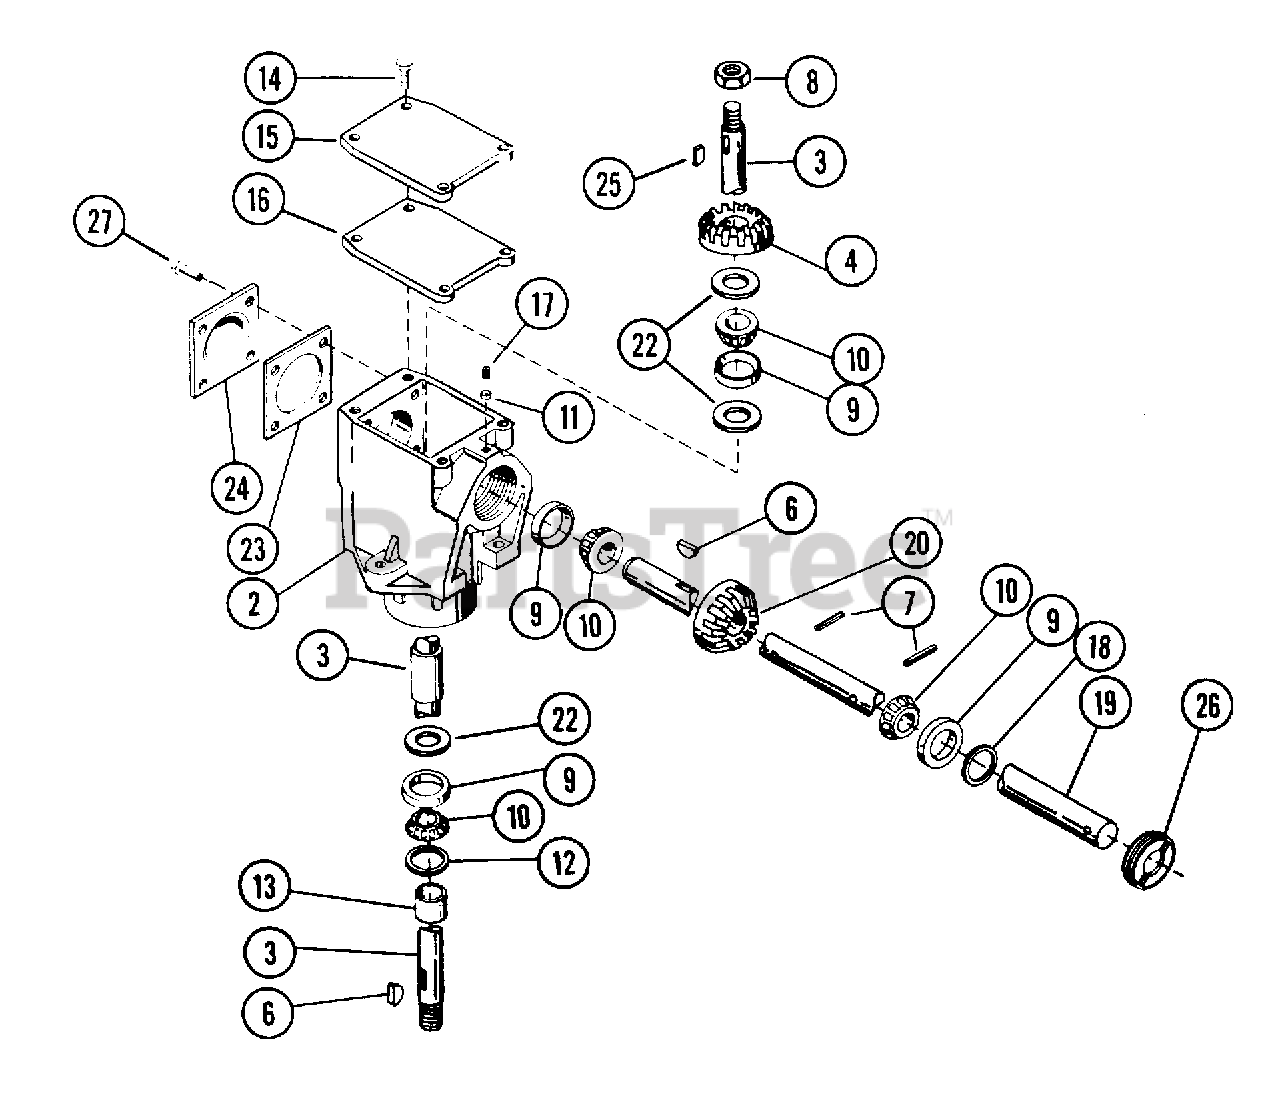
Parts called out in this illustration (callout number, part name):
2	GEAR CASE
3	SHAFT, OUTPUT
4	GEAR
6	KEY, WOODRUFF .25X.75X.312
7	PIN, SPRING .187X1.250
8	NUT, HEX JAM CENTER LOCK 9/16-18
9	BEARING, CUP LM 11910
10	BEARING, CONE LM 11949
11	PLUG
12	SEAL
13	SPACER
14	SCREW, TAPPING #8-32X.375 HWHPL
15	COVER
16	GASKET
17	SCREW, SET 1/4-20X.375 HS CP
18	SEAL
19	SHAFT
20	GEAR
22	WASHER, .774/.811X1.000X.003
22	WASHER, .774/.811X1.000X.015
22	WASHER, .774/.811X1.000X.025
22	WASHER, .749/.759X1.000X.032
23	GASKET, SIDE COVER
24	COVER
25	KEY, STRAIGHT .25X.65X.25
26	PLUG
27	SCREW, TAPTITE 5/16-18X.75
